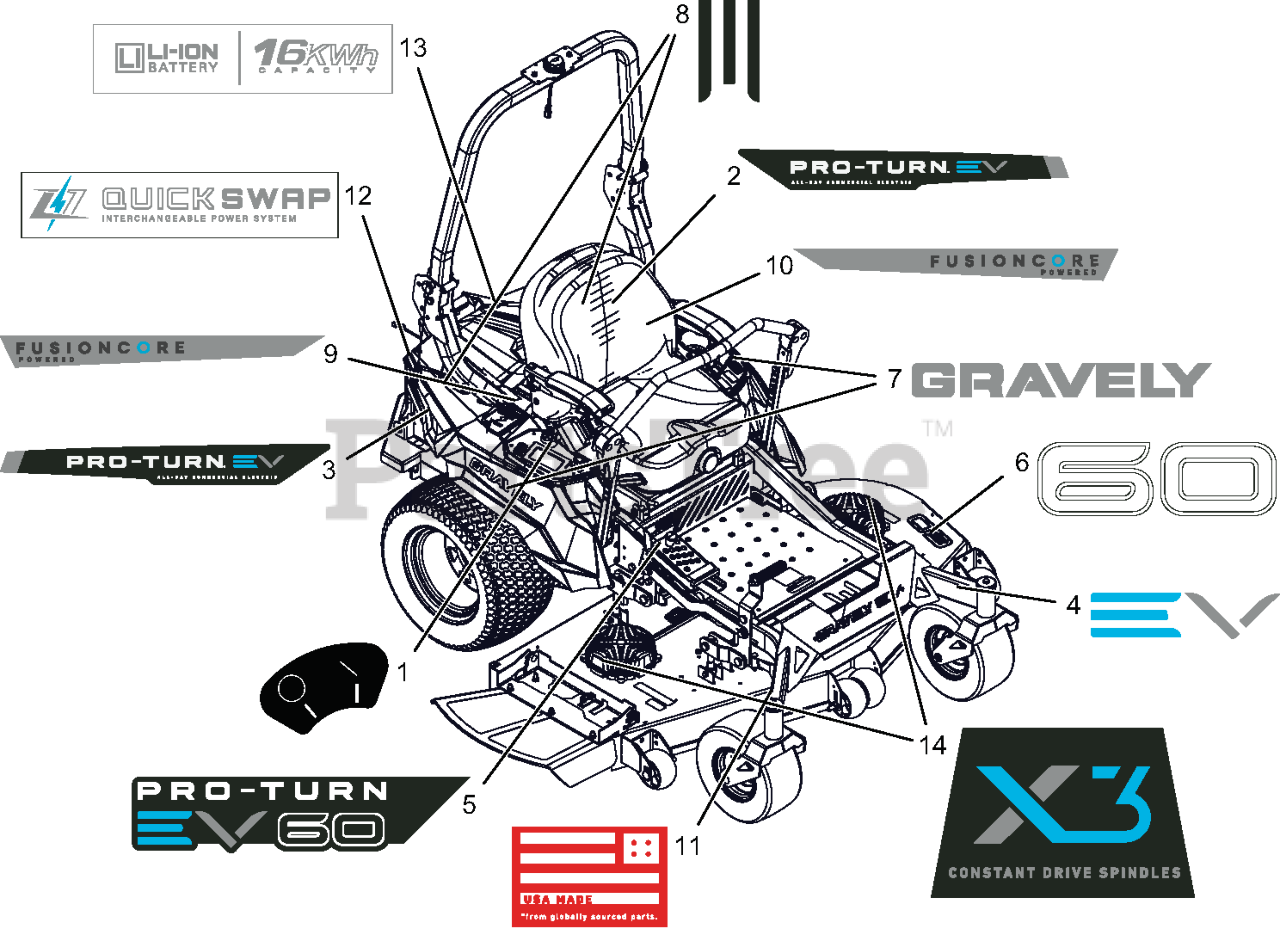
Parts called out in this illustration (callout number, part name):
1	DECAL, KEY SWITCH - 2POS
2	DECAL, FENDER - LH
3	DECAL, FENDER - RH
4	DECAL, FRONT FORK
5	DECAL, KICK PLATE
6	DECAL, DECK - 60"
7	DECAL, GRAVELY LOGO
8	DECAL, STRIPE
9	DECAL, FUSION CORE - LEFT
10	DECAL, FUSION CORE - RIGHT
11	DECAL, USA MADE
12	DECAL, QUICK SWAP -HATCH
13	DECAL, LI- ION - HATCH
14	DECAL, DECK MOTOR
